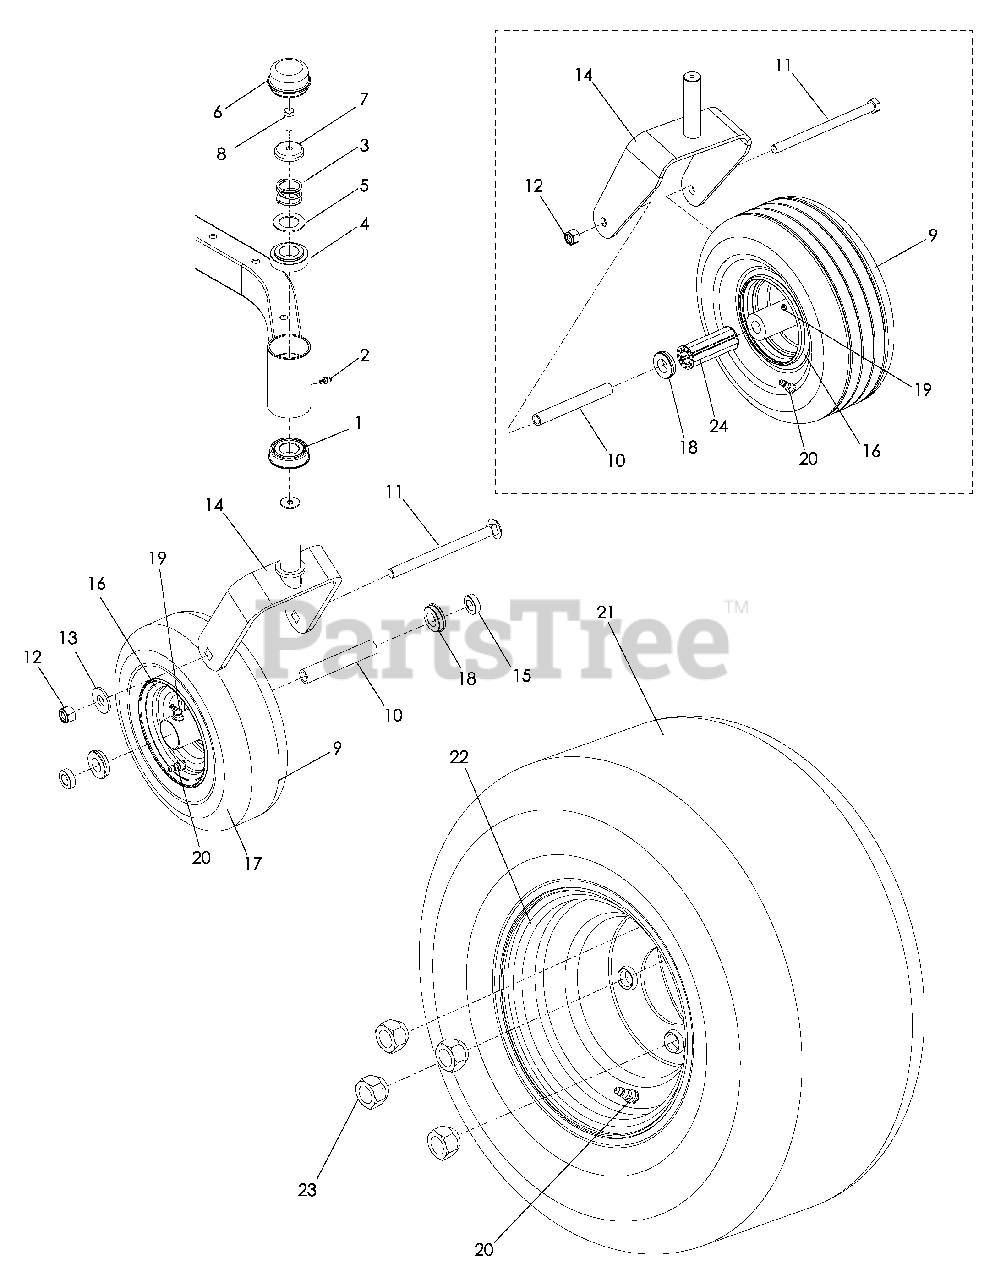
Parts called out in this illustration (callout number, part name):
1	BEARING, FLANGED
2	ZERK 3/16 DRIVE
3	SPRING, CASTER
4	BUSHING, CASTER
6	GREASE CAP
7	PLUG, CASTER
8	HCS 5/16-18 x 1
9	CASTER TIRE ASSM 965880801, 965881001
10	SPACER 965880801, 965881001
11	RHSNB ½-13 x 6½ 965880801, 965881001
12	NUT ½-13 HEX NYLOC
13	WASHER ½ FLAT
14	YOKE 965880801, 965881001
15	SPACER 5/16 965880801, 965881001
16	RIM 965880801, 965881001
17	CASTER TIRE, 410/350 4 PLY 965880801, 965881001
18	BEARING, FLANGED
19	ZERK 965880801, 965881001
20	VALVE STEM
21	TIRE, REAR ASSM 22 x 9.5 965880901
22	RIM 8 x 7 w/ .8" OFFSET 965880801, 965881001
23	NUT ½-20 LUG
24	BEARING 965880901
